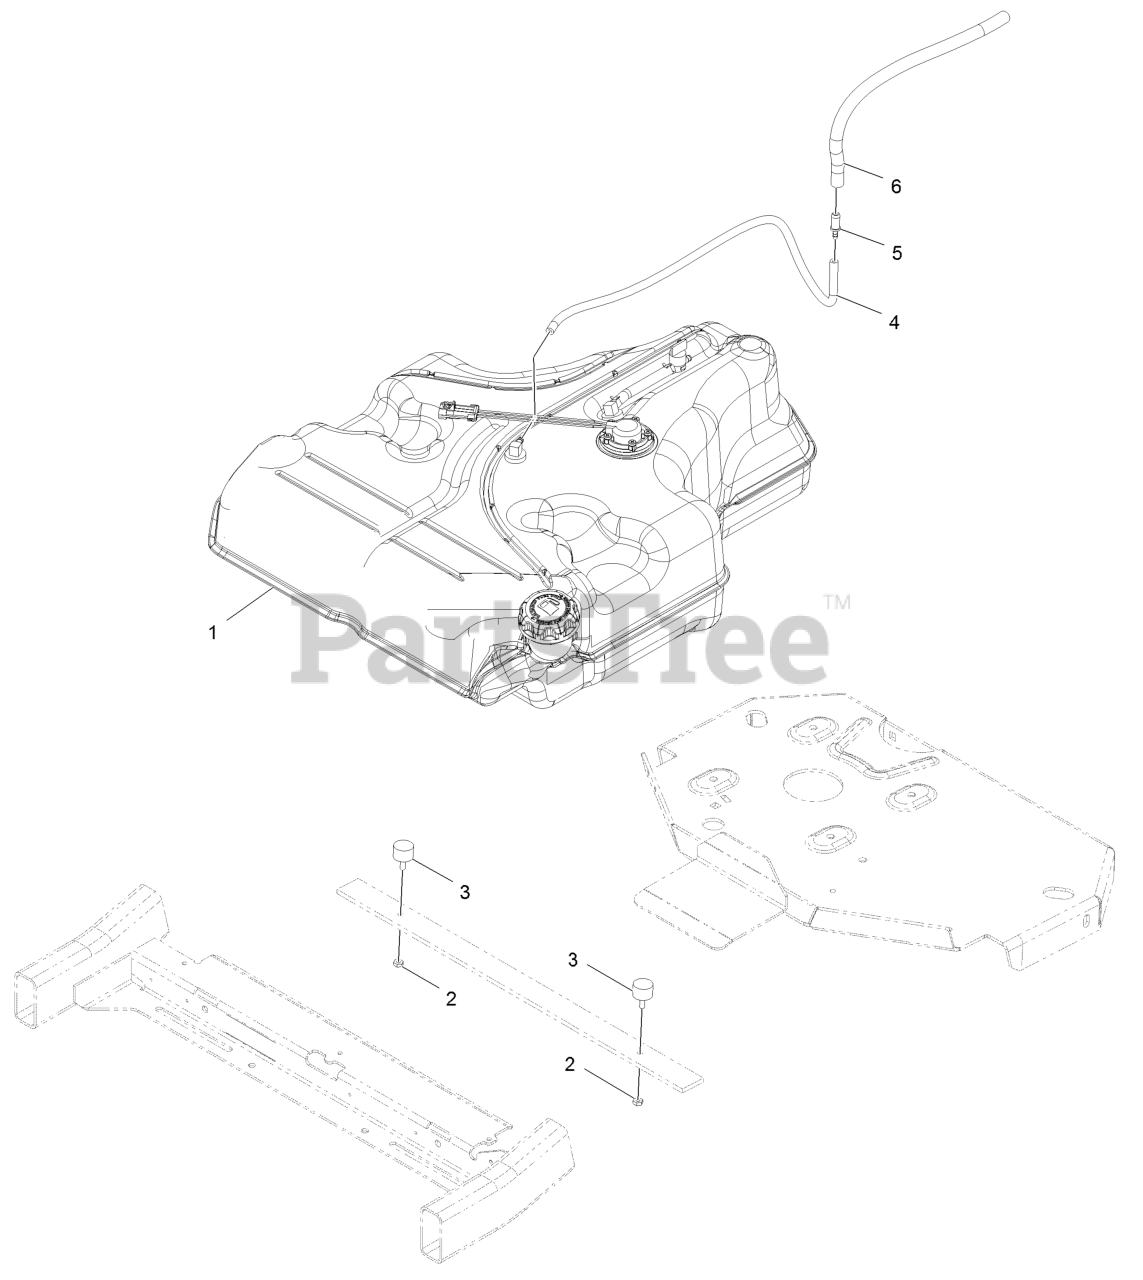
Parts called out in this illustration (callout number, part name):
2	NUT-JAM
4	HOSE-FUEL
5	FITTING-STRAIGHT
6	HOSE-FUEL
